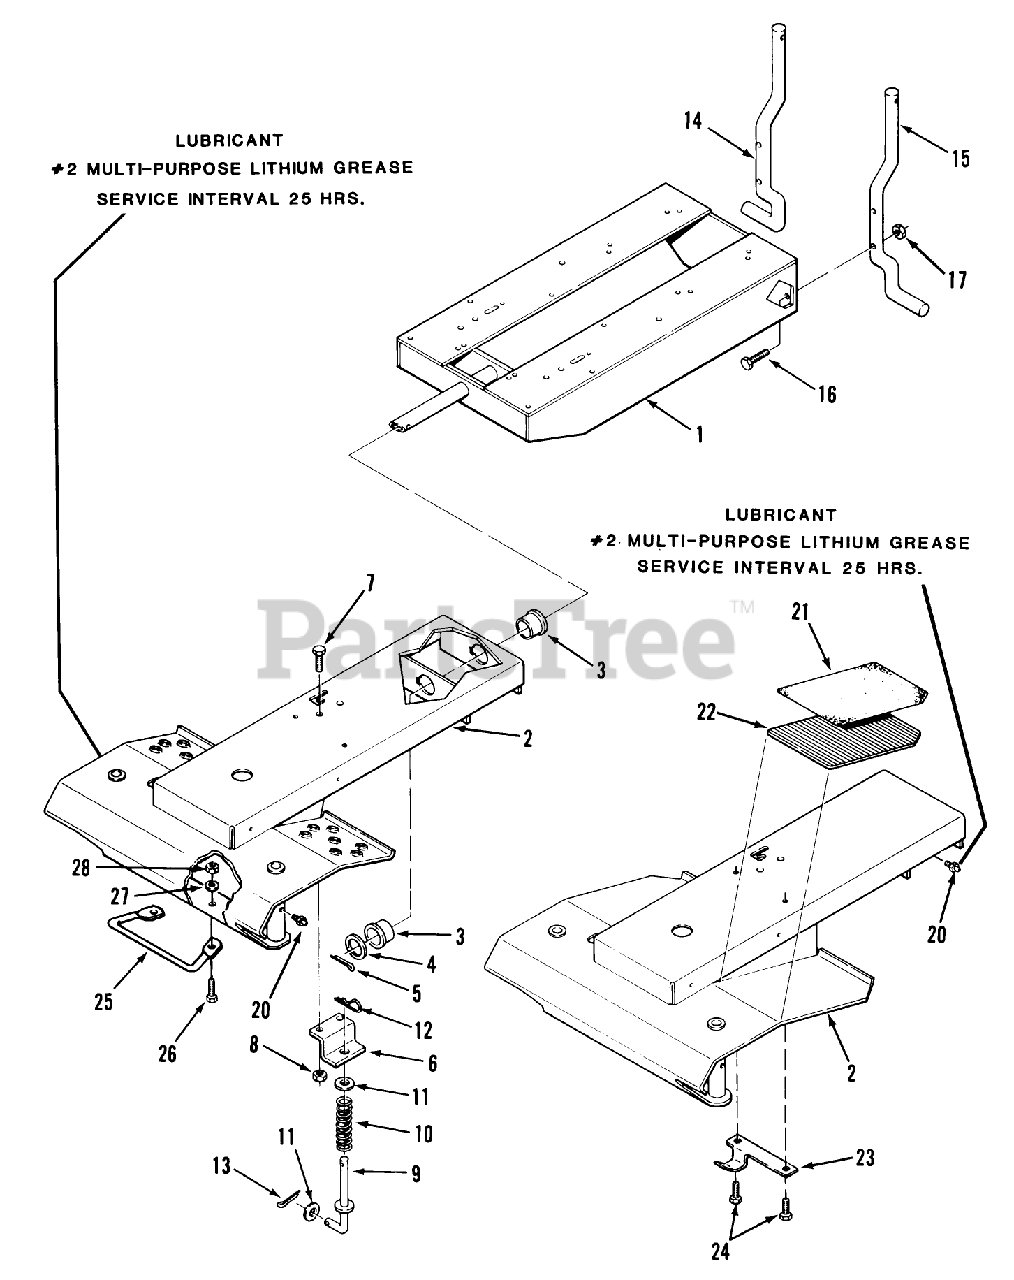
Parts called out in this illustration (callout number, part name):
1	ASS'Y-FRAME REAR *R
10	SPRING-COMPRESSION
12	Hairpin Cotter
14	REAR ROD RH *B
15	REAR ROD LH *B
22	PAD FOOTREST RH
24	Screw
27	WASHER 5/16 SAE
